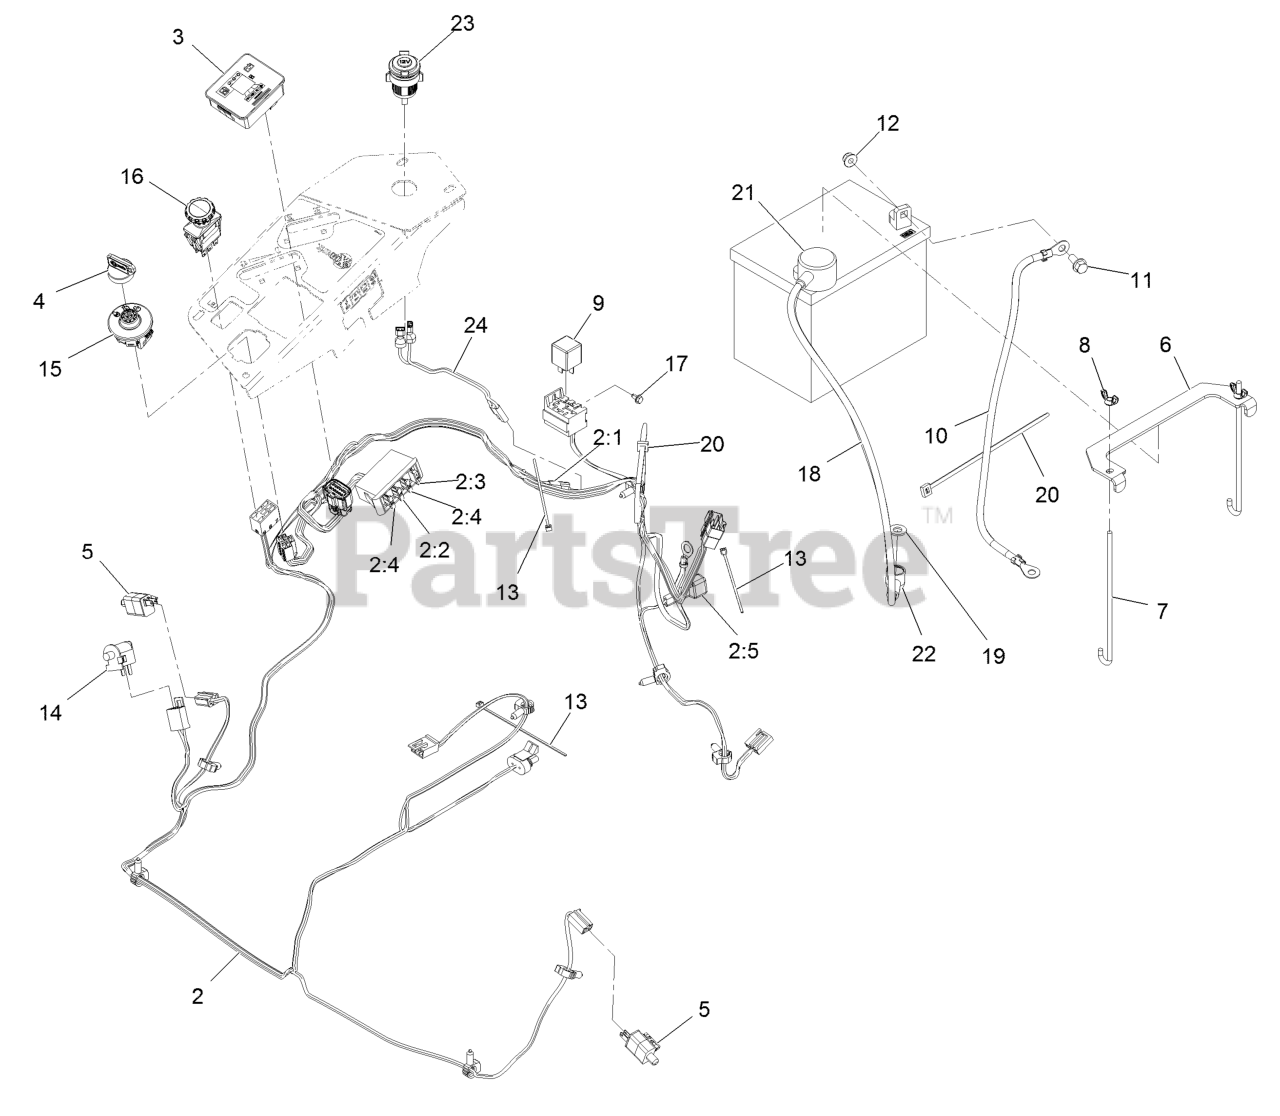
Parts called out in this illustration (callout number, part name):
2	HARNESS-WIRE, MAIN
2:2	FUSE-BLADE, 10 AMP
2:3	FUSE-BLADE, 15 AMP
2:4	FUSE-BLADE, 25 AMP
2:5	CAP-PLUG
3	FUEL/HOUR METER ASM
4	KEYS-IGNITION (SPARE PAIR
4	KEY-IGNITION
6	STRAP-TIE DOWN, BATTERY
7	BOLT-HOLDDOWN
8	WINGNUT
10	CABLE-BATTERY, NEGATIVE
11	SCREW-HHF
12	NUT-HF, NI
13	TIE-CABLE
14	SWITCH-BAIL
16	SWITCH-PTO, 10 AMP
17	SCREW-HWH
18	CABLE-BATTERY, POSITIVE
19	WASHER-FLAT
20	TIE-PLASTIC
21	INSULATOR-BATTERY
22	INSULATOR-SOLENOID
23	RECEPTACLE-12V
24	HARNESS, RECEPTACLE 12V
